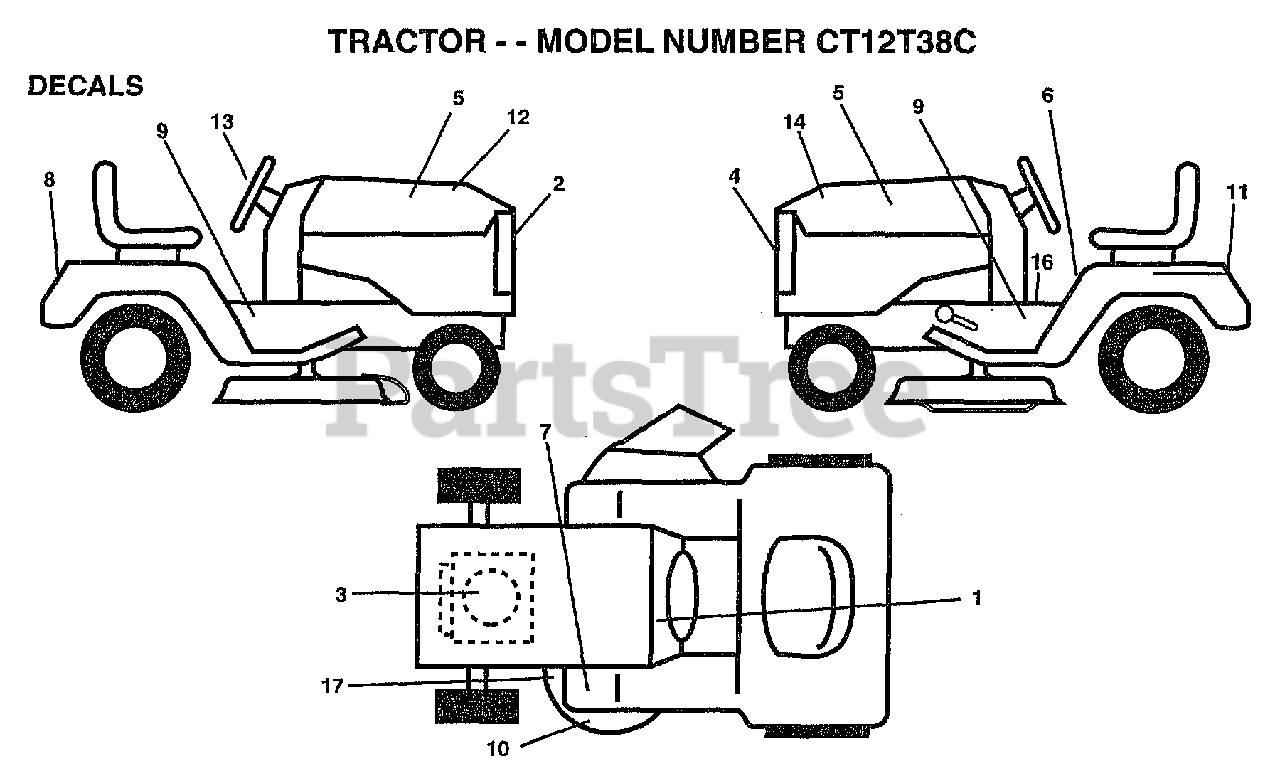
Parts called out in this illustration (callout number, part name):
1	"DECAL-OPER,GEAR D"
2	GRILL DECAL
5	DECAL.HOOD.INS.
6	"DECAL DANGER,FEND"
8	FENDER DECAL
9	DECAL CHASSIS SPEED DECK
11	DECAL.BATRY.3-3908
12	DECAL HOOD RH RLY
13	"DECAL,STR WHL"
14	DECAL HOOD LH RLY
16	DECAL BRAK PARK
17	DECAL
